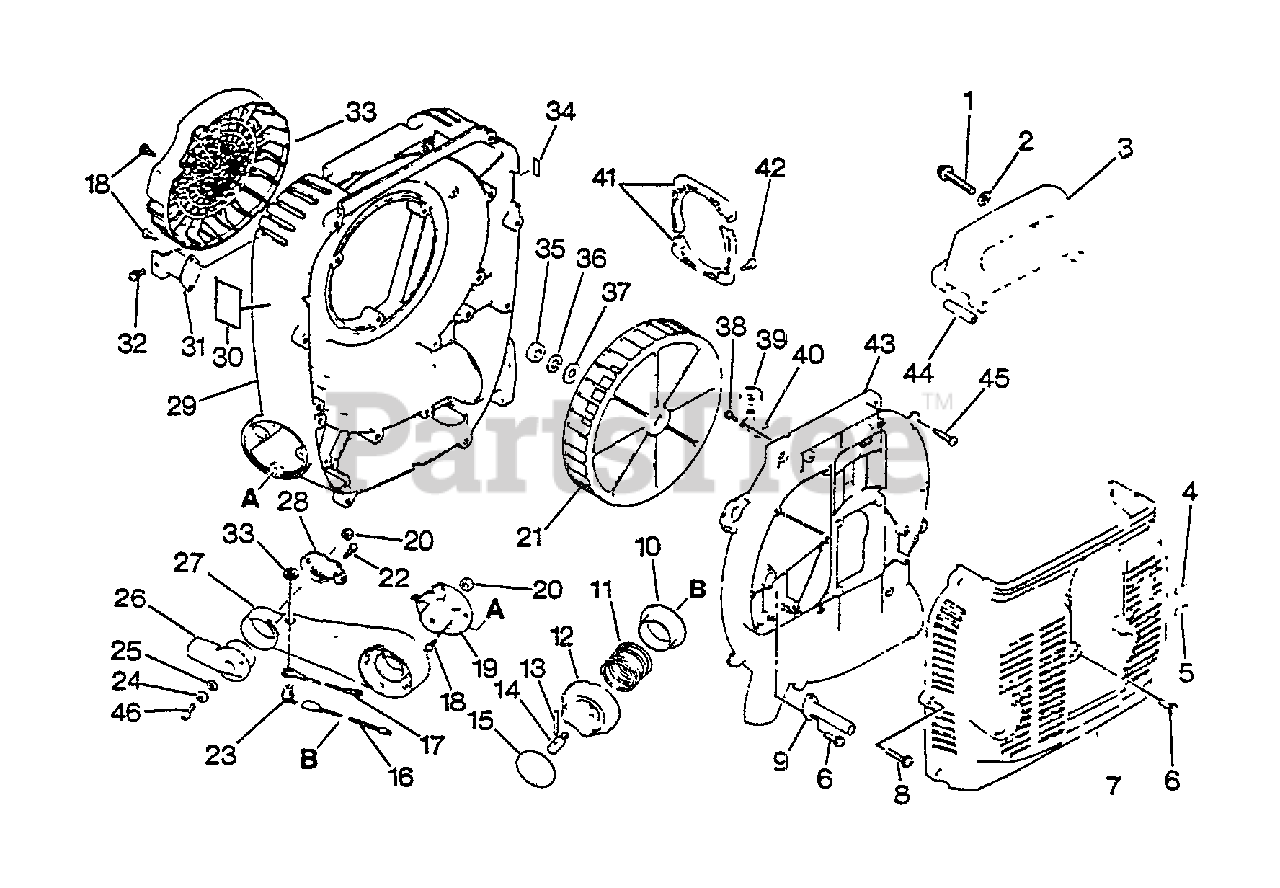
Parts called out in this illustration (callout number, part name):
1	SCREW - 6X70
2	WASHER - 6
4	LABEL - IDLE
5	LABEL - CAUTION
6	SCREW - 4X14
7	COVER, ENGINE
8	SCREW - 5X20
9	DUCT, AIR
10	SEAT, SPRING
12	KNOB
15	LABEL
16	LEAD - IGNITION
17	LEAD - GROUND
18	SCREW - 5X14
19	PLATE
20	LOCKNUT - 6
22	SCREW - 4X10
23	IGNITION SWITCH ASSY
25	WASHER - 6
26	TRIGGER, THROTTLE
27	ARM, THROTTLE CONTROL
28	BRACKET, THROTTLE
29	COVER, FAN - INNER
30	LABEL - CAUTION
32	SCREW - 5X14
33	GUARD, DEBRIS
34	LABEL - CHOKE
35	NUT - 10
36	LOCKWASHER - 6
37	WASHER - 10
38	SCREW - 4X10
40	PIPE - INTAKE
41	BRACKET
42	SCREW - 5X14
43	COVER, FAN - OUTER
45	SCREW - 5X25
46	SCREW - 6X20
